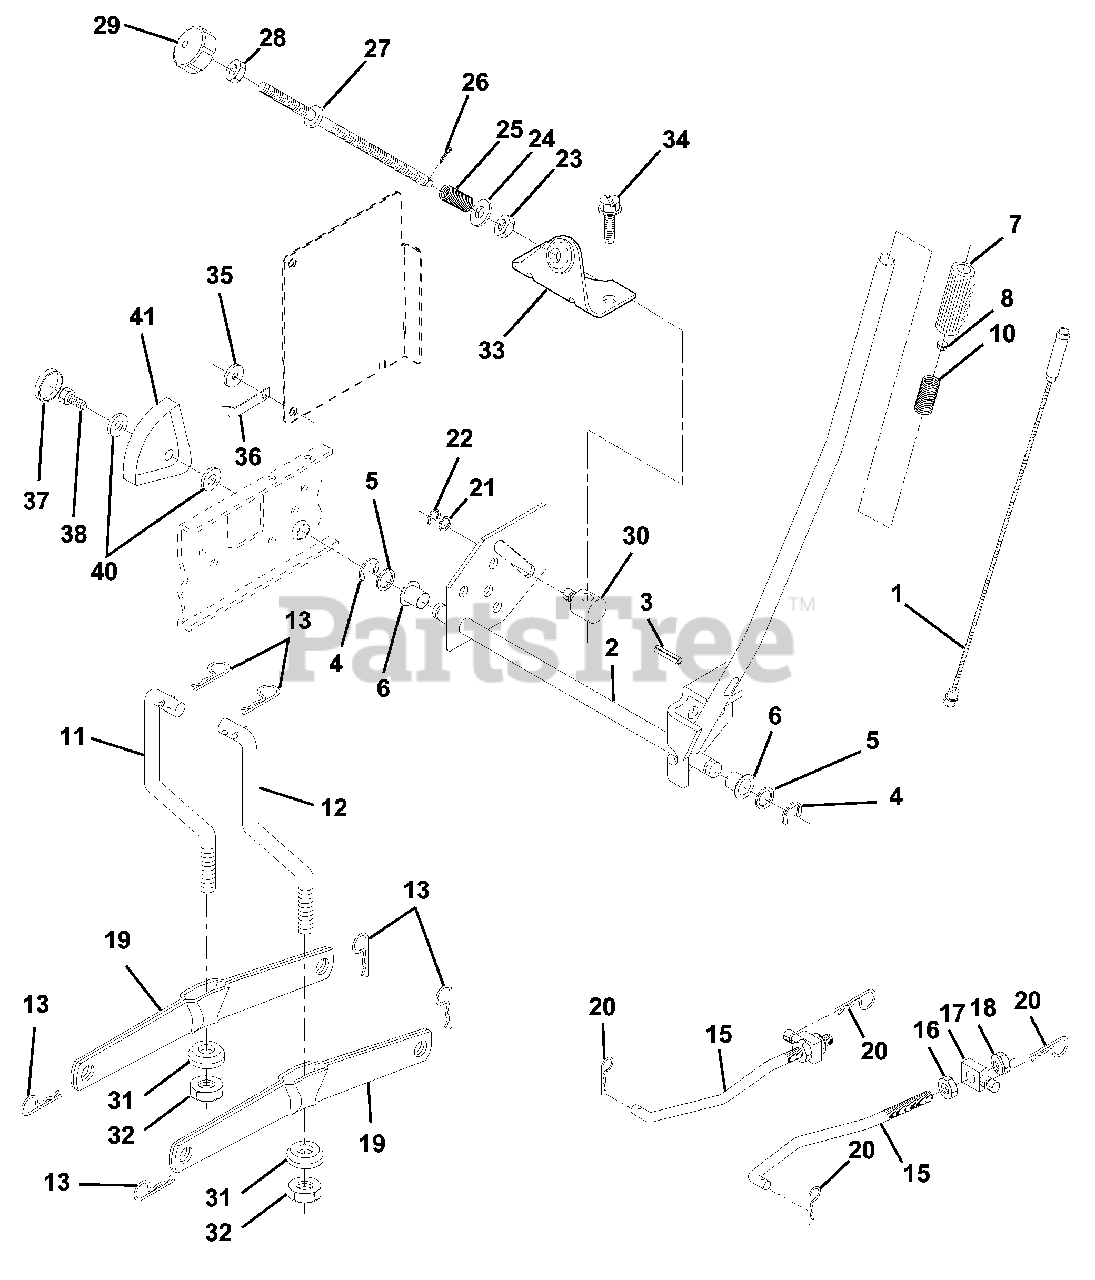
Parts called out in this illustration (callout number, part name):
1	Wire Asm Inner W/plunger 17.32
2	Shaft Asm Lift RH w/Inf
3	Pin Groove 1 500 Zinc
4	E Ring #5133-62
5	Washer 21/32 X 1 X 21 Ga
6	Bearing Nylon Blk 629 Id
7	Grip Handle Fluted Blk
8	Button Plunger Black
10	Spring Cprsn 3 750 Oiled
11	Link Lift LH
12	Link Lift RH
13	Retainer Spring
15	Link Front
16	Nut Jam Hex 1/2-13 Unc
17	Trunnion Blk Zinc
18	Nut Lock W/wsh 1/2-13unc
19	Arm Suspension Rear
20	Retainer Spring
21	Washer 15/32 X 3/4 X 16 Ga
22	Ring Klip #t5304-37
23	Nut Special
24	Washer 13/32 X 5/8 X 16 Ga
25	Spring Compression Inf. Hgt.
26	Pin Cotter 3/32 X 1/2
27	Rod Adj Lift Zinc 7.49 Wrk Lg
28	Nut Hex Jam 3/8-16 Unc
29	Knob Inf 3/8-16 Unc Blk W/sym
30	Trunnion Dp Stop Dbl Thds PLT
31	Bearing Pvt Lift Spherical
32	Nut Crownlock 3/8-24
33	Bracket, Stop Inf. Hgt.
34	Screw, Thdrol 3/8-16 x 1/2 Ty-TT
35	Washer Nylon .44 x .75 x .032
36	Pointer Height Indicator
37	Plug Hole Blk 1.485/1.515
38	Screw Thdrol 5/16-18 x 3/4 TYT
40	Washer 11/32 x 1-1/2 x 10 Ga.
41	Scale Ind. Height Blk
